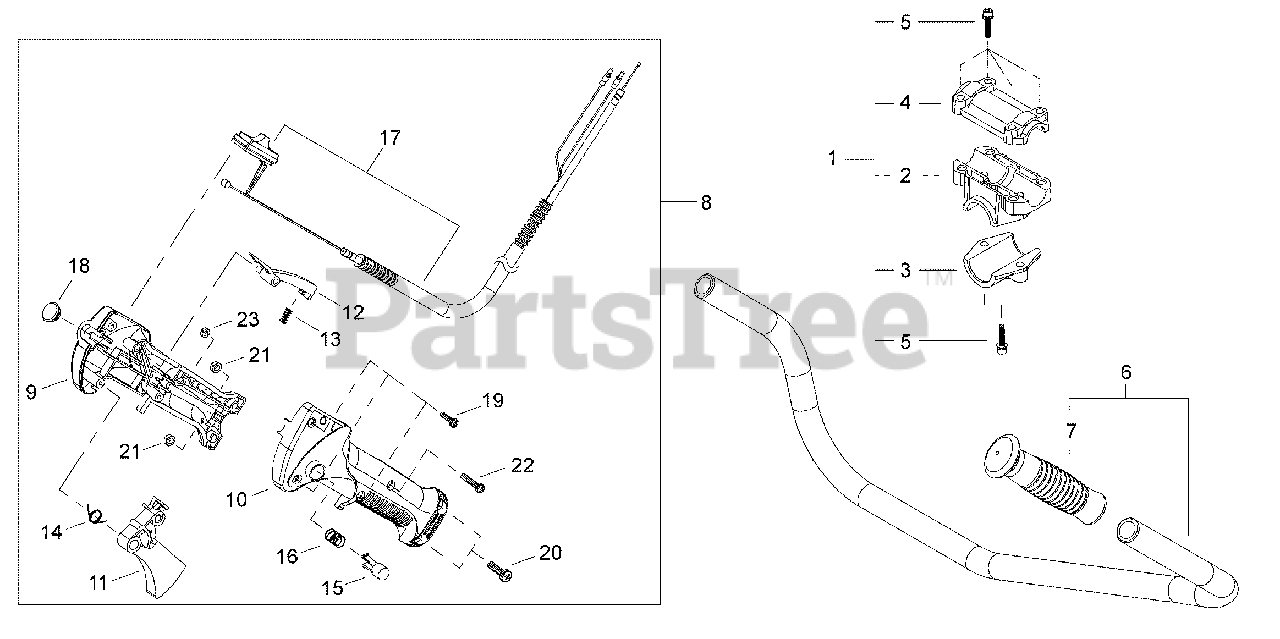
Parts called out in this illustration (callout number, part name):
1	HANDLE BRACKET KIT
2	BRACKET, HANDLE - LOWER
3	BRACKET, MOUNTING
4	BRACKET, HANDLE - UPPER
5	SCREW - 5X25
6	HANDLE ASSY
7	GRIP - LEFT
8	THROTTLE CONTROL ASSY
9	HANDLE, CONTROL - RIGHT
10	HANDLE, CONTROL - LEFT
11	TRIGGER, THROTTLE
12	LEVER, TRIGGER LOCKOUT
13	SPRING
14	SPRING
15	BUTTON, THROTTLE LOCK
16	SPRING
17	IGNITION SWITCH ASSY
18	PLUG
19	SCREW - 4X16 -- TAPPING
20	SCREW - 5X20
21	NUT - 5
22	SCREW - 4X23
23	NUT - 4
